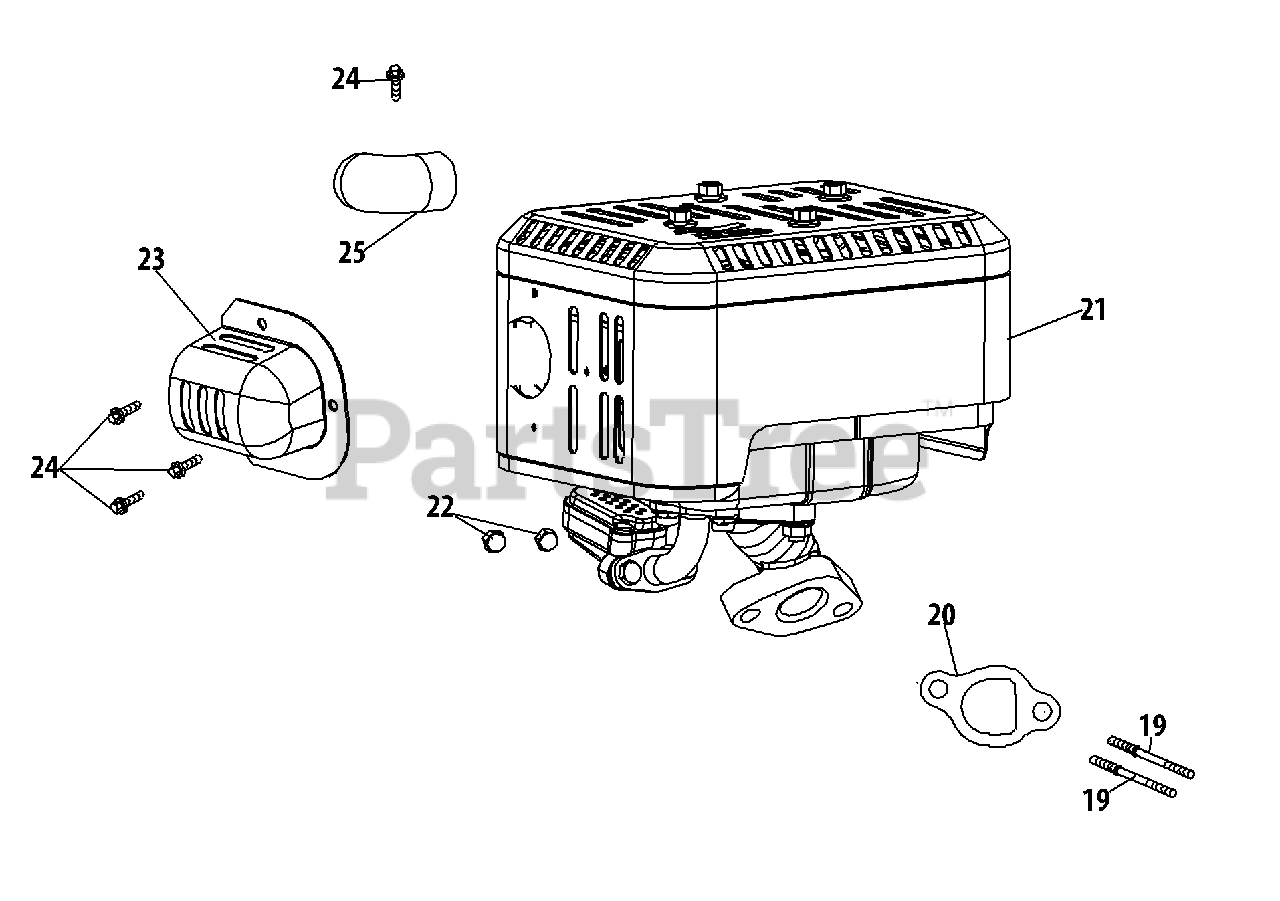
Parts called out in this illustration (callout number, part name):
19	Stud M8×38
19	Muffer Stud Kit
20	Exhaust Pipe Gasket
21	Muffler Assembly
22	Nut,M8
23	Exhaust Pipe Shield
24	Duct Bolt
25	Muffler Deflector
